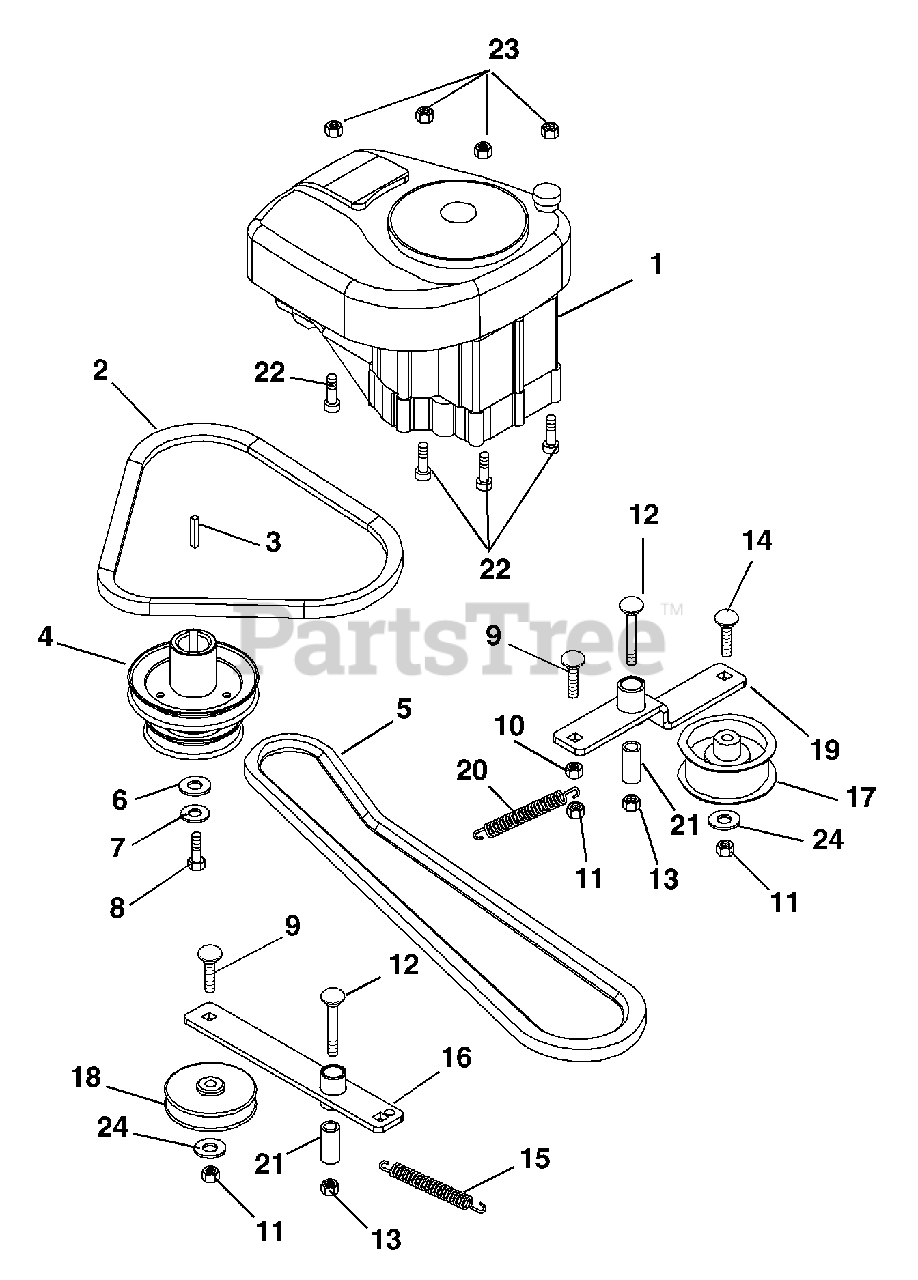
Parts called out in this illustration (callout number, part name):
1	GROUP-ENG 12HP INTEK AVS
1	ENG GROUP 10HP INTEK AVS
1	GROUP-ENG 14HP INTEK AVS
2	V-BELT, 4L-RAW EDGE
3	KEY-STR .25X1.75X.25
4	STACK, RER ENGINE SHEAVE
4	STACK, RER 40" DECK SHEAVE
5	V-BELT, HA-WRAPPED
5	KIT, 28" CUTTING IMPROVEMENT
6	WSHR-FL-STL.463X1.375X.25 YWZC
7	@WSHR-LK .44X.109 REG YWZC
8	BLT-HEX .44-20X1.75 GR5 YWZC
9	@BLT-RDHDSQNK .38-16X1.50 G5YZ
10	@NUT-SPNLK-FLG .375-16 YWZC
11	NUT-LK-TOP-FLG .38-16 BLKZC
12	BLT-RDHDSQSHNK .50-13X2.75 BZC
13	@NUT-LK-TOP-FLG .50-13 YWZC
14	@BLT-RDHDSQNK .38-16X2.00 G5YZ
15	SG-TENS .095X.500X5.5 WLD60 YZ
16	IDLER, DRIVE (WLDMNT)
17	IDLER 2.75X1.25
18	IDLER-V 3X.38
19	IDLER, RER PTO (WLDMNT)
19	IDLER, 40" DECK PTO
20	SG-TENS .093X.75X4.0 WLD40
21	BSHG-SLV .500X.750X1.560
22	SCR-SKH BTHD .31-18 X 1.50 GR8
23	NUT-LK-TOP-FLG .31-18 BLKZC
24	@WSHR-FL-STL.38X.875X.083 YWZC
